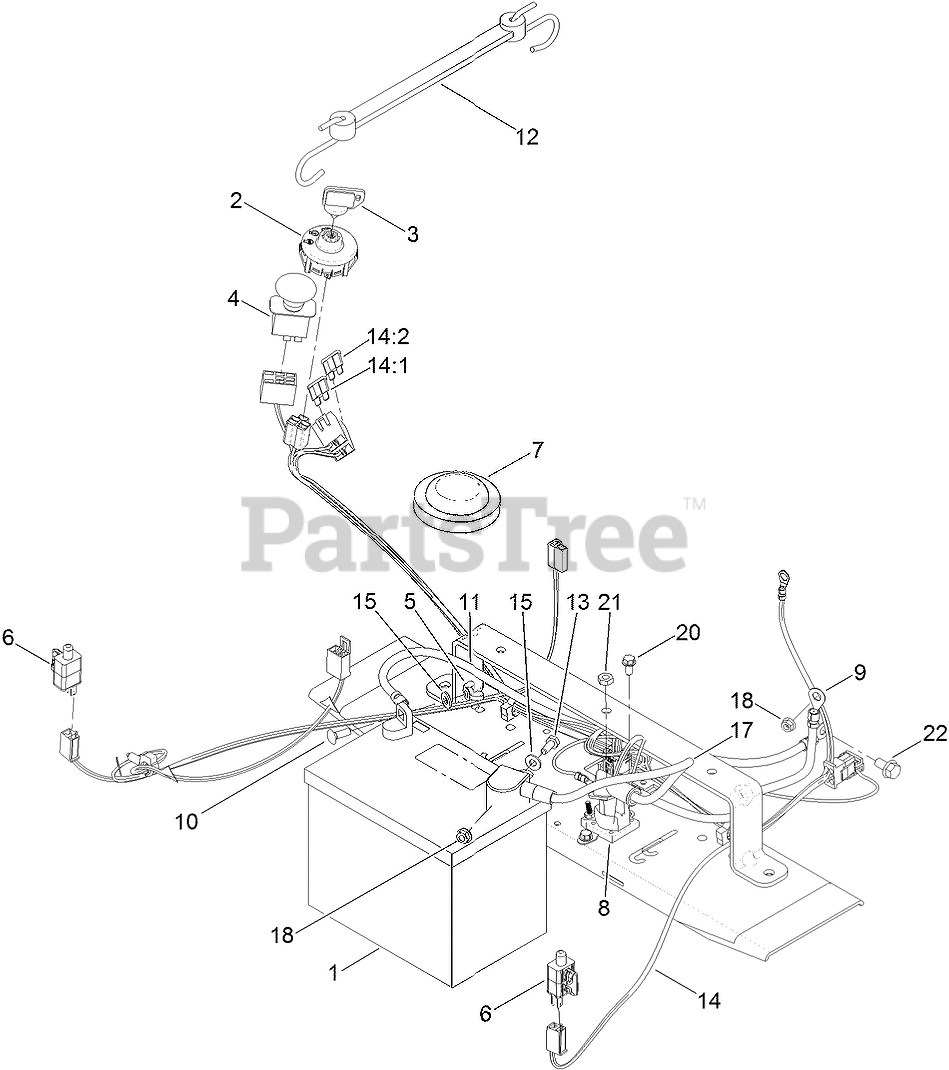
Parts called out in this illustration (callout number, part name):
1	BATTERY
2	SWITCH-IGNITION
3	KEY-IGNITION
4	SWITCH-PTO
5	NUT-WING
6	SWITCH
7	SWITCH-SEAT
8	SOLENOID
9	CABLE-BATTERY, RED
10	BOLT-CARR
11	CABLE-BATTERY, BLACK
12	HOLDDOWN-BATTERY
13	SCREW-HH
14	HARNESS-WIRE
14:1	FUSE-BLADE, 30 AMP
14:2	FUSE-BLADE, 25 AMP
15	WASHER-FLAT
17	CABLE-BATTERY, RED
18	NUT-HF
20	SCREW-HWH
21	NUT-JAM
22	SCREW-HHF
